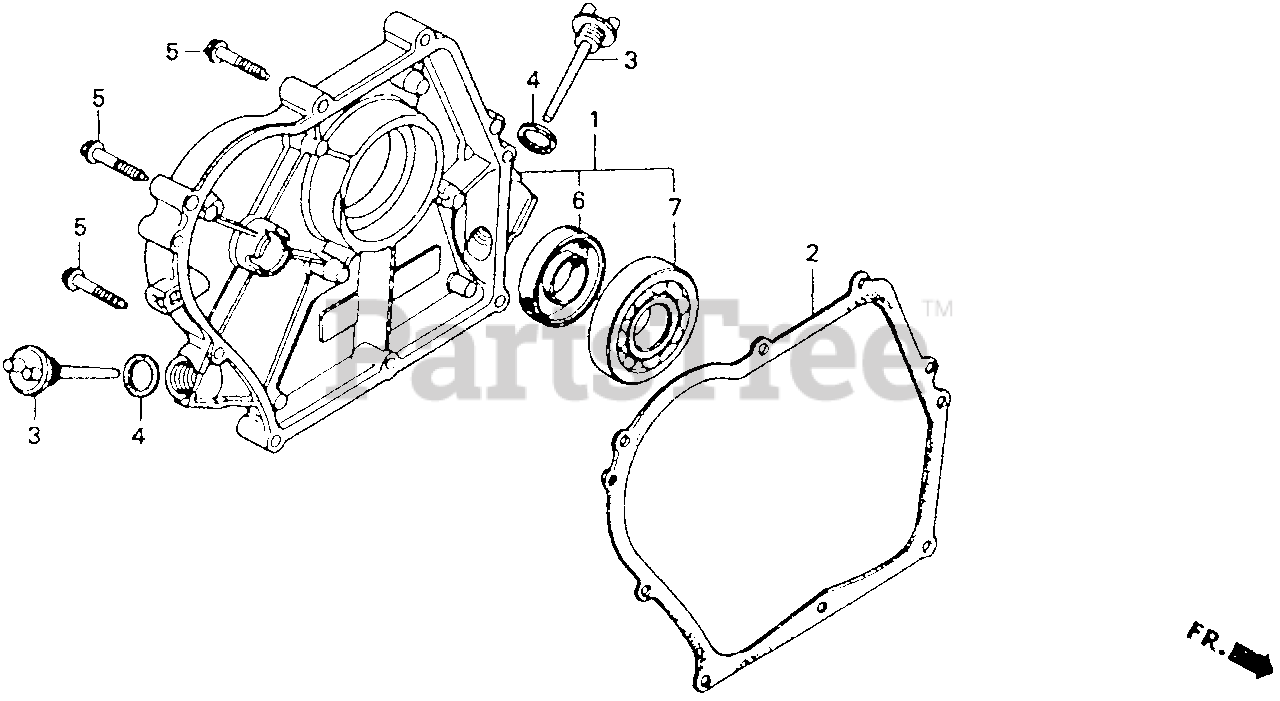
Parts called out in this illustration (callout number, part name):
1	COVER ASSY., CRANKCASE (Q-TYPE)
1	COVER ASSY., CRANKCASE (U-TYPE)
2	GASKET, COVER
3	CAP, OIL
4	GASKET, OIL FILLER CAP
5	BOLT, FLANGE (6X32)
6	OIL SEAL (25X41X6)
7	BEARING, RADIAL BALL (6205)
